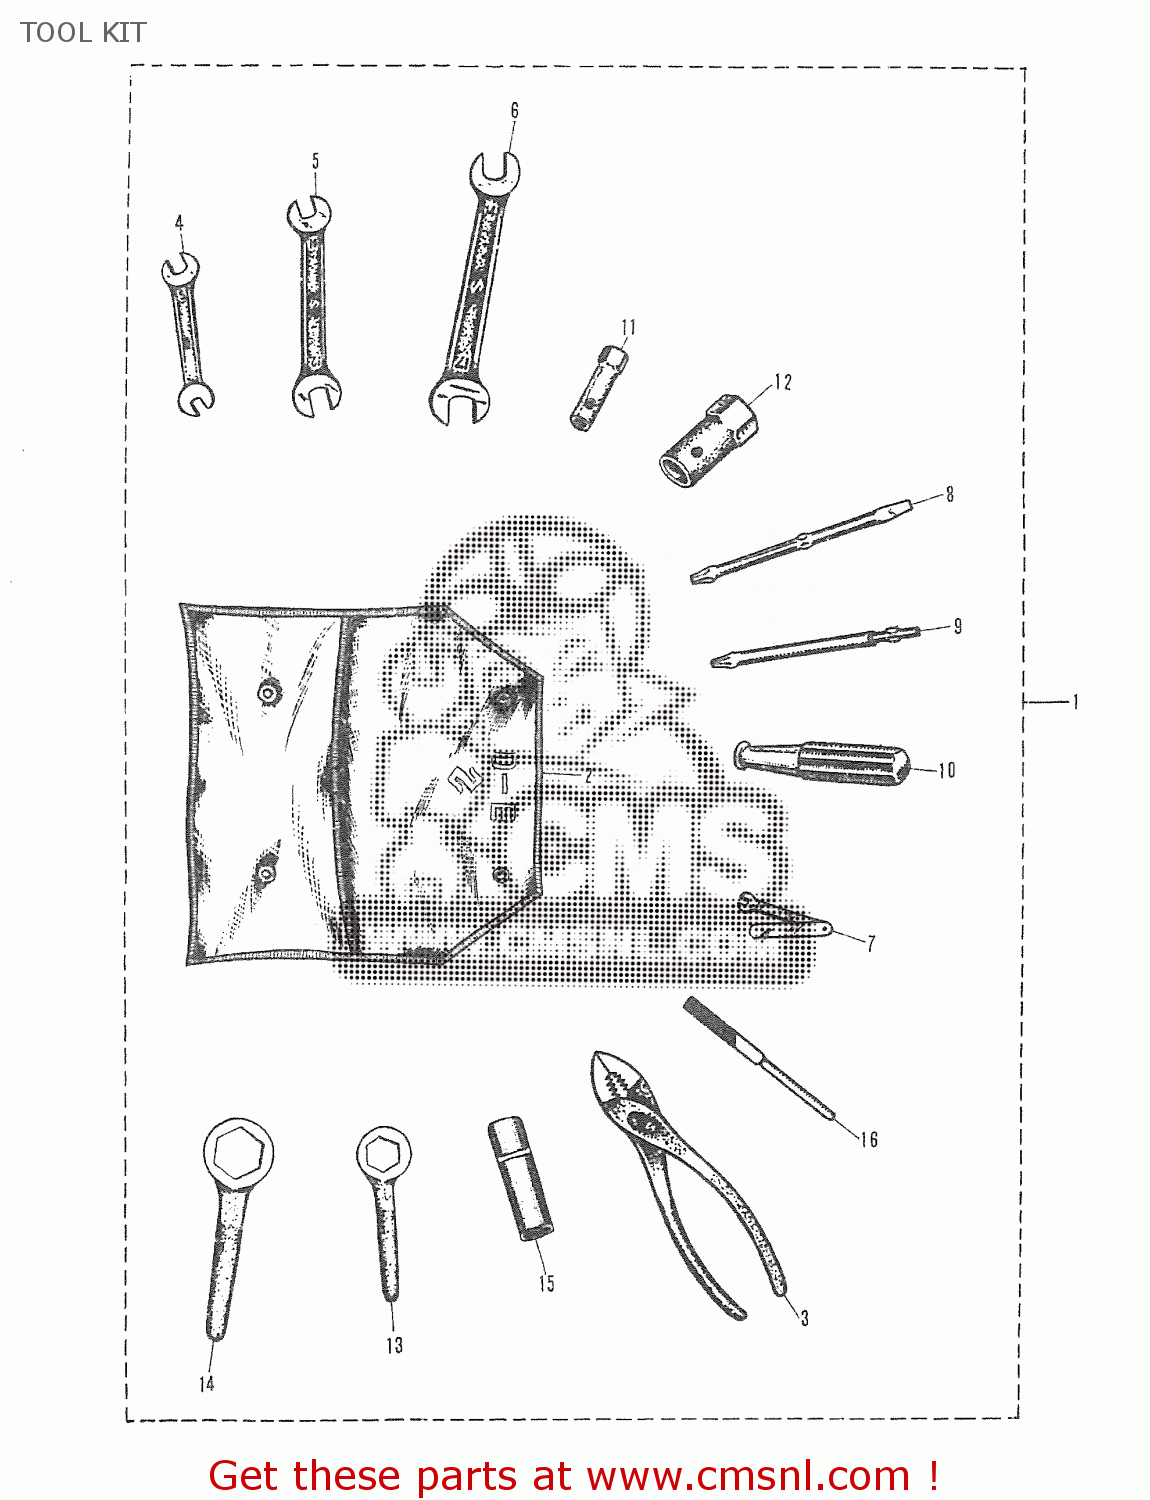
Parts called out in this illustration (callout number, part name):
1	TOOL ASSY
2	TOOL BAG
3	COMBINATION PLIERS
4	8X9MM OPEN END WRENCH
5	10X12MM OPEN END WRENCH
6	14X17MM OPEN END WRENCH
7	POINT WRENCH
8	COMBINATION SCREW DRIVER
9	CROSS SCREW DRIVER
10	GRIP, SCREW DRIVER R,J,K,L,M
11	14MM BOX WRENCH
12	21MM BOX WRENCH
13	23MM OFFSET WRENCH
14	32MM OFFSET WRENCH
15	WRENCH HANDLE
16	CONTACT POINT FILE
